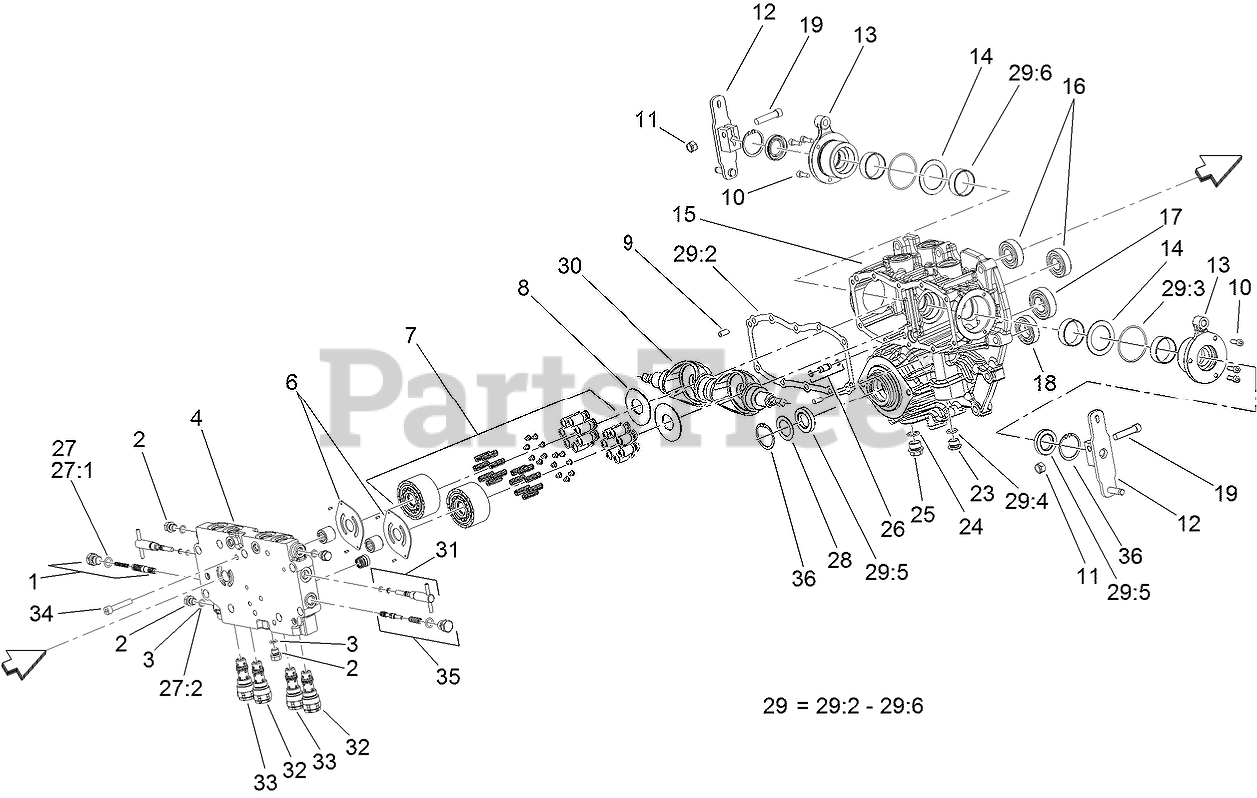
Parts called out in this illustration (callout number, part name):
1	VALVE-FLUSHING, RH
3	O RING-PLUG
4	CENTER CASE, COMPLETE
6	PLATE-VALVE
7	CYLINDER BLOCK ASM
8	PLATE-THRUST
9	PIN-PARALLEL
12	ARM-CONTROL
13	SIDE COVER ASM
15	PUMP HOUSING ASM
16	BEARING
17	BEARING
18	BEARING
23	PLUG-NPTF
24	O-RING
27	CENTER CASE SEAL KIT
27:2	O RING-PLUG
29	PUMP HOUSING SEAL KIT
29:2	GASKET-CASE, CENTER
29:3	O RING-PLUG
29:4	Packing
29:6	RING-SEAL
30	PLATE-SWASH
31	VALVE-BYPASS
32	VALVE-REAR
33	VALVE-FRONT
35	VALVE-FLUSHING, LH
36	RING-SNAP
